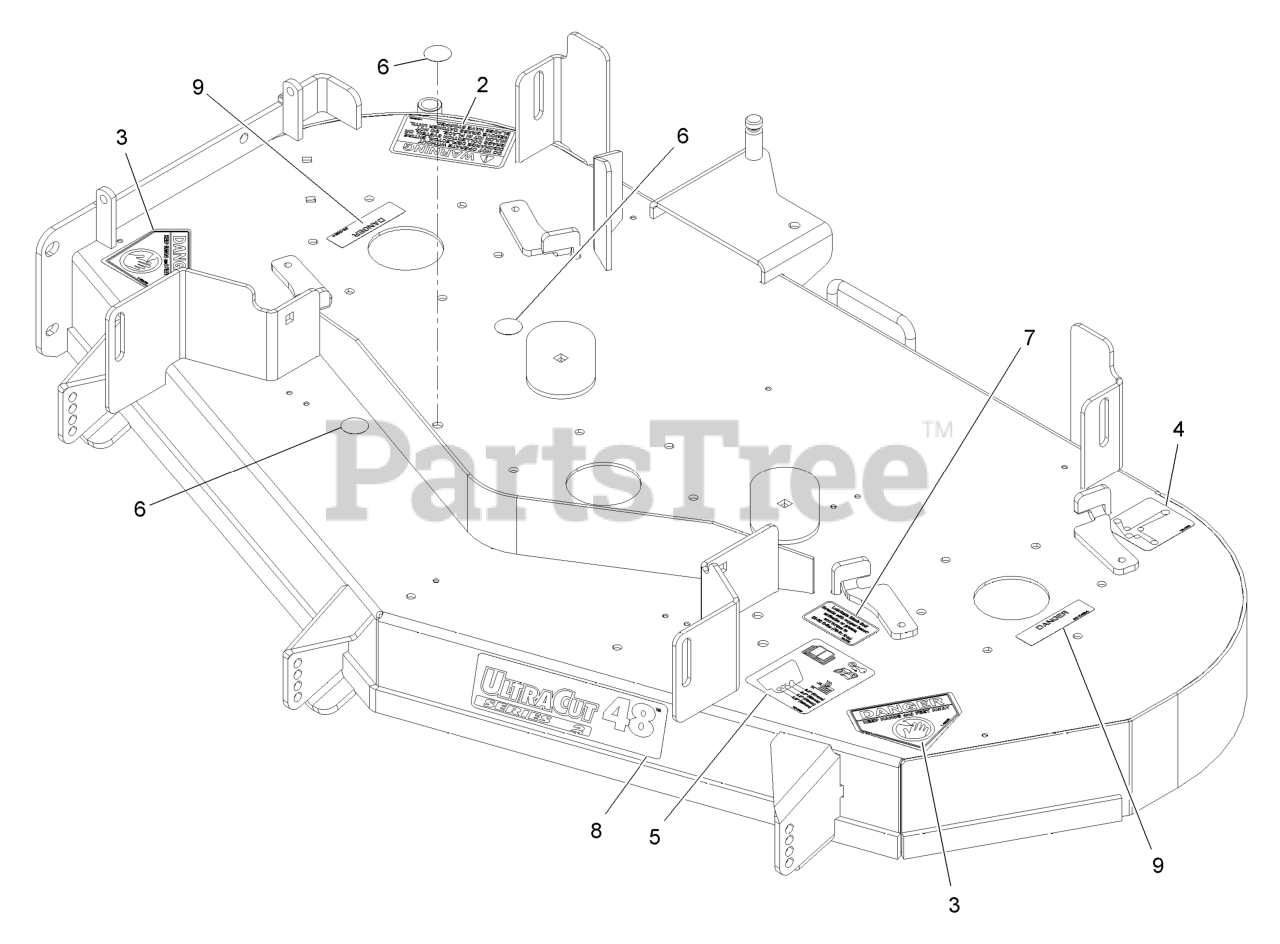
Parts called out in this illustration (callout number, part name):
2	DECAL-WARNING, DISCHARGE
3	DECAL-DANGER
4	DECAL-ROUTING, BELT
5	DECAL-ROLLER, ANTI-SCALP
6	DECAL-HOLE COVER
7	DECAL,BOLT TORQUE
8	DECAL-ULTRACUT 48 SERIES
9	DECAL-COVER, MISSING
